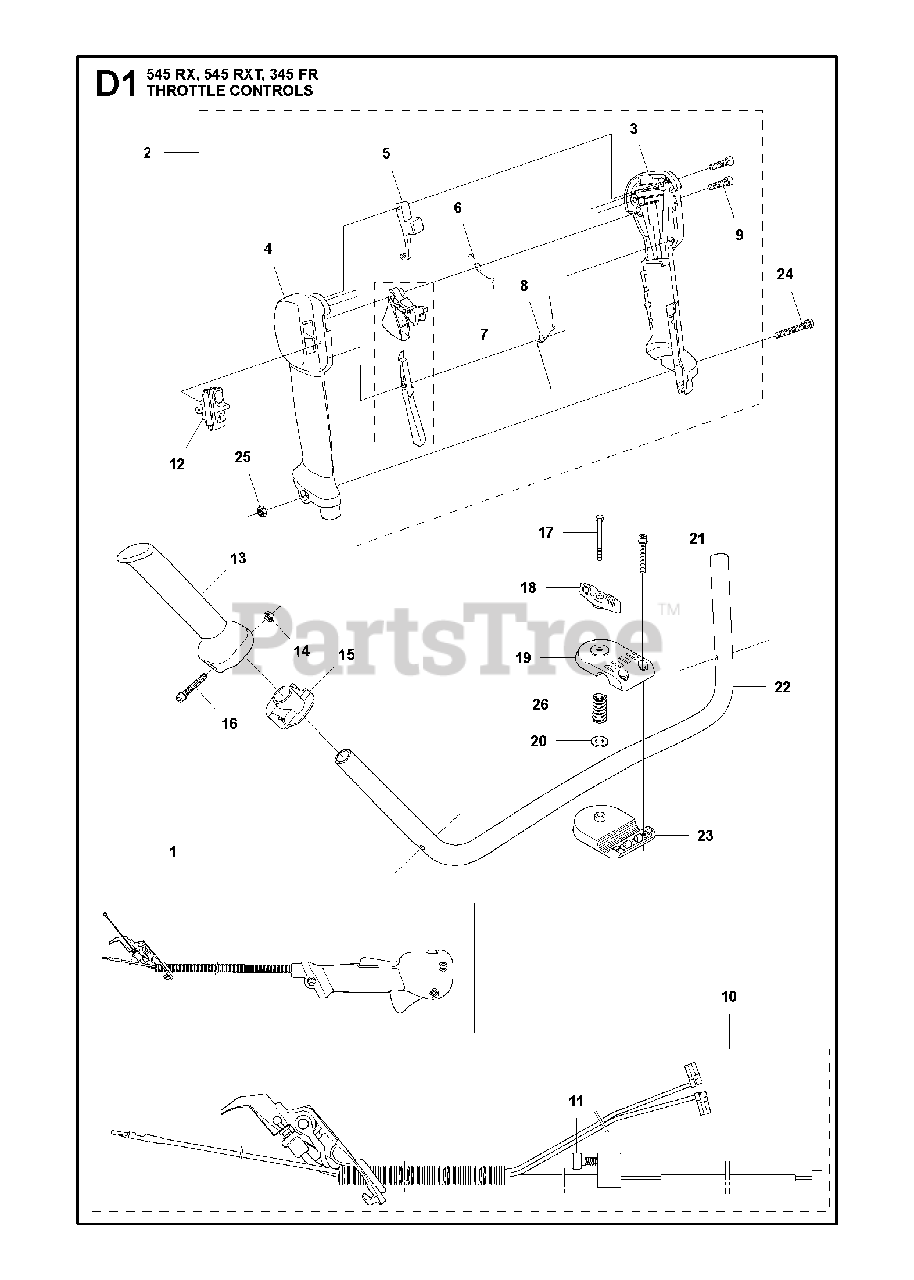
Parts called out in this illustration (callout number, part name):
1	THROTTLE HANDLE ASSY
2	THROTTLE HANDLE ASSY
3	HANDLE HALF RIGHT
4	HANDLE HALF LEFT
5	STARTER THROTTLE LOCK
6	SPRING
7	THROTTLE CONTROL
8	SPRING
9	SCREW
11	SCREW
12	STOP BUTTON
14	NUT M6M M5
19	HANDLE HOLDER UPPER
23	HANDLE HOLDER LOWER
24	SCREW IHSCFM
